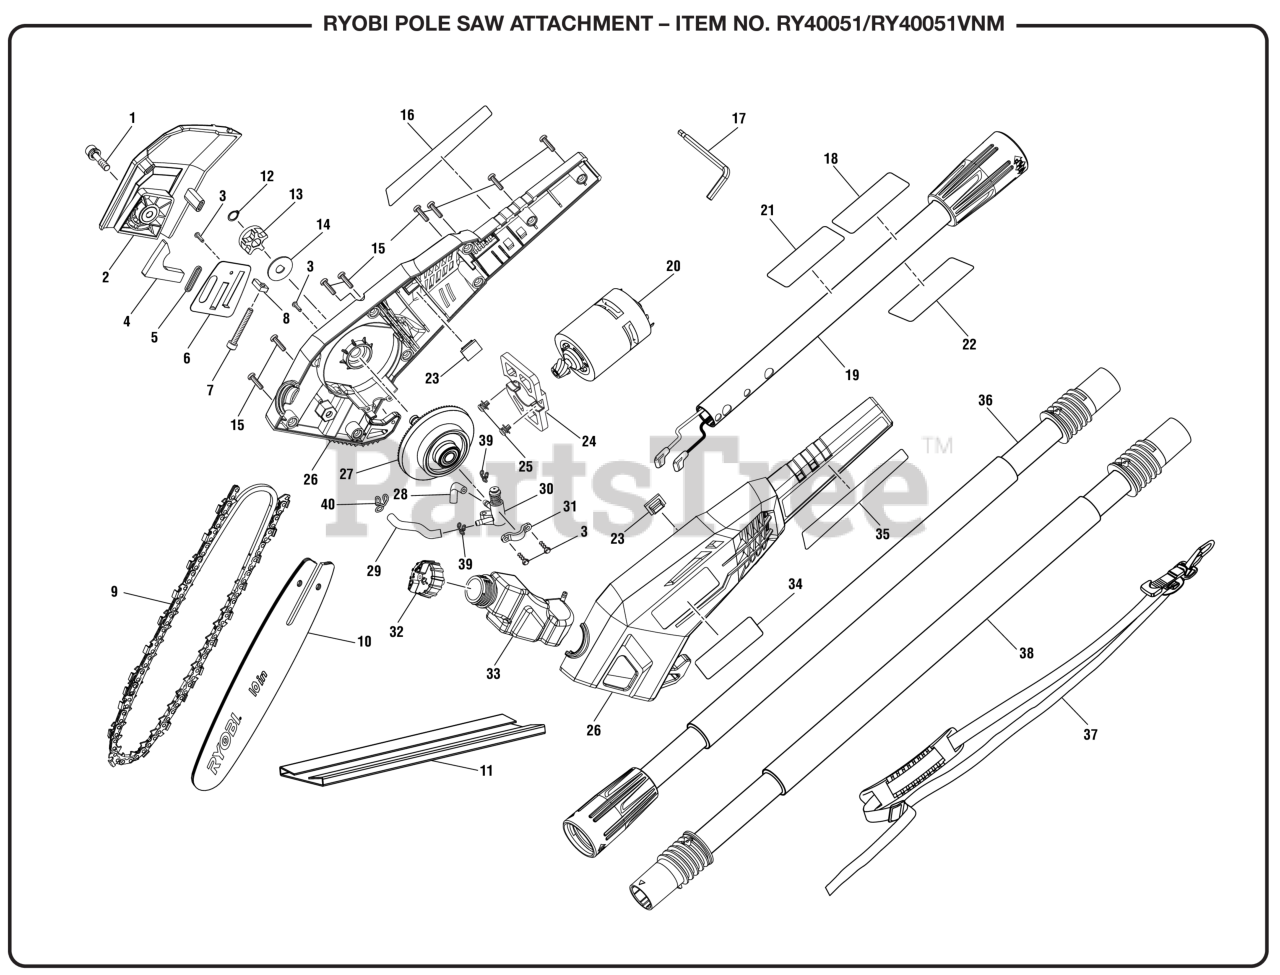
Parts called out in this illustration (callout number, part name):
1	Screw w/Washer (M6 x 25 mm, Rd. Hd. )
2	Chain Cover Assembly
3	Screw (M3 x 8 mm, Pan Hd., Pan Hd)
4	Chain Cover Seal Ring
5	Oil Outlet Seal Ring
6	Guide Bar Plate
7	Screw (M5 x 37 mm, Soc. Hd.)
8	Adjustment Block
9	Chain (10 in.)
10	Guide Bar
12	Retaining Ring
14	Cover Plate (Internal "D" Washer)
15	Screw (M4 x 18 mm, T20 Torx Pan Hd.)
16	40V Lithium Label (Right)
17	Hex Key (5 mm)
18	Icon Warning Label (English)
19	Upper Pole Assembly
20	Motor Assembly
21	Data Label
22	Warning Label (French/Spanish)
23	Rubber Bumper
24	Mounting Plate
25	Screw w/Washer (M5 x 9 mm, Pan Hd.)
26	Motor Housing Assembly
27	Output Shaft Assembly
28	Inlet Tube
29	Outlet Tube
30	Oil Pump Assembly
31	Pump Clamp
32	Oil Tank Cap Assembly
33	Oil Tank Assemlby
34	Logo Label
35	40V Lithium Label (Left)
36	Extended Boom Assembly
37	Shoulder Strap Assembly
38	Boom Assembly
39	Clip-hose (Id 4.9)
40	Clip-hose
